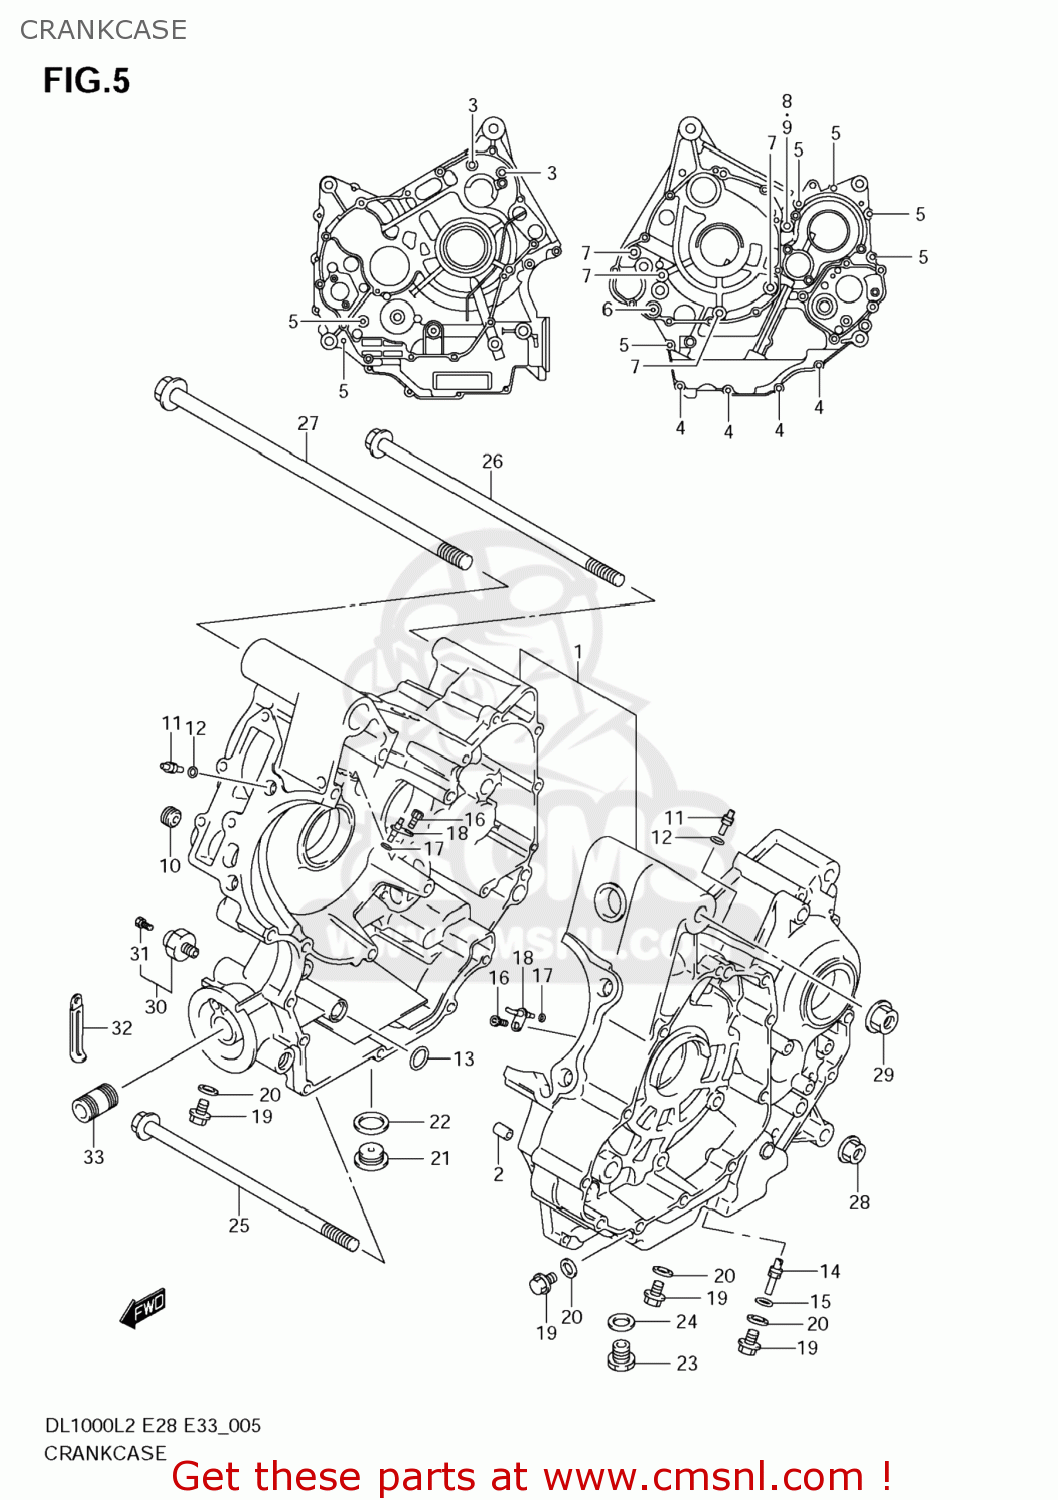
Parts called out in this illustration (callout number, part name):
1	CRANKCASE SET
2	PIN,CRANKCASE
3	BOLT(8X110)
4	BOLT
5	BOLT
6	BOLT
7	BOLT
8	BOLT(8X125)
9	WASHER
10	JET,OIL GALLERY(3.6)
11	JET,AIR(14)
12	O RING(D:1.2,ID:4)
13	O RING(D:1.9,ID:12.6)
14	JET,OIL GALLERY
15	O RING(D:1.2,ID:4)
16	BOLT(6X12)
17	O RING(D:1.2,ID:4.7)
18	JET,PISTON COOLING
19	BOLT
20	GASKET(8.2X14X1) (NAS)
21	PLUG,16X8
22	GASKET(16X22X2) (NAS)
23	PLUG(14X20)
24	GASKET(13.8X18.8X4.8) (NAS)
25	BOLT(10X225)
26	BOLT(10X275)
27	BOLT(12X330)
28	NUT
29	NUT
30	SWITCH ASSY,OIL PRESSURE
31	BOLT,OIL PRESSURE SWITCH
32	CLAMP(L:45)
33	UNION,OIL STAND
